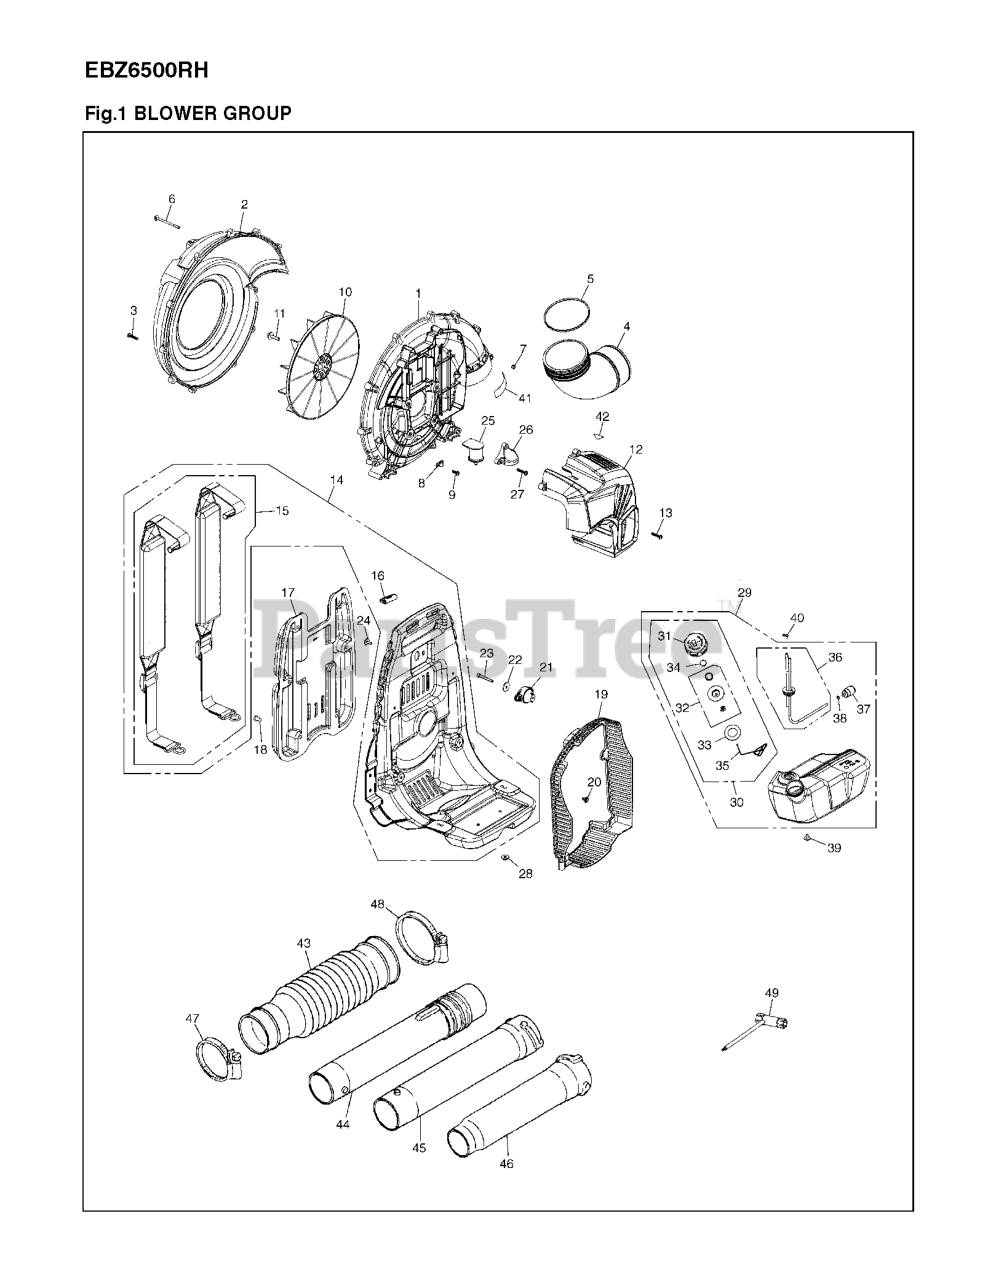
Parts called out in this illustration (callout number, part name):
1	VOLUTE, CASE
2	VOLUTE, CASE
5	0-RING
8	CLAMP
12	ENGINE COVER
14	FRAME ASSY
15	BAND ASSY (RPLS 848L583611)
16	CLIP
18	CLIP
19	NET
20	CLIP
21	DAMPER UPPER
23	BOLT
29	TANK ASSY
30	ASSY FUEL CAP
32	HOLDER-A
36	PIPE
37	FILTER ASSY
38	CLIP
40	CLIP
44	SWIVEL JOINT
46	PIPE, END (RPLS 848L5C65E0)
47	CLAMP(F96)
48	CLAMP(F115)
49	SOCKET
